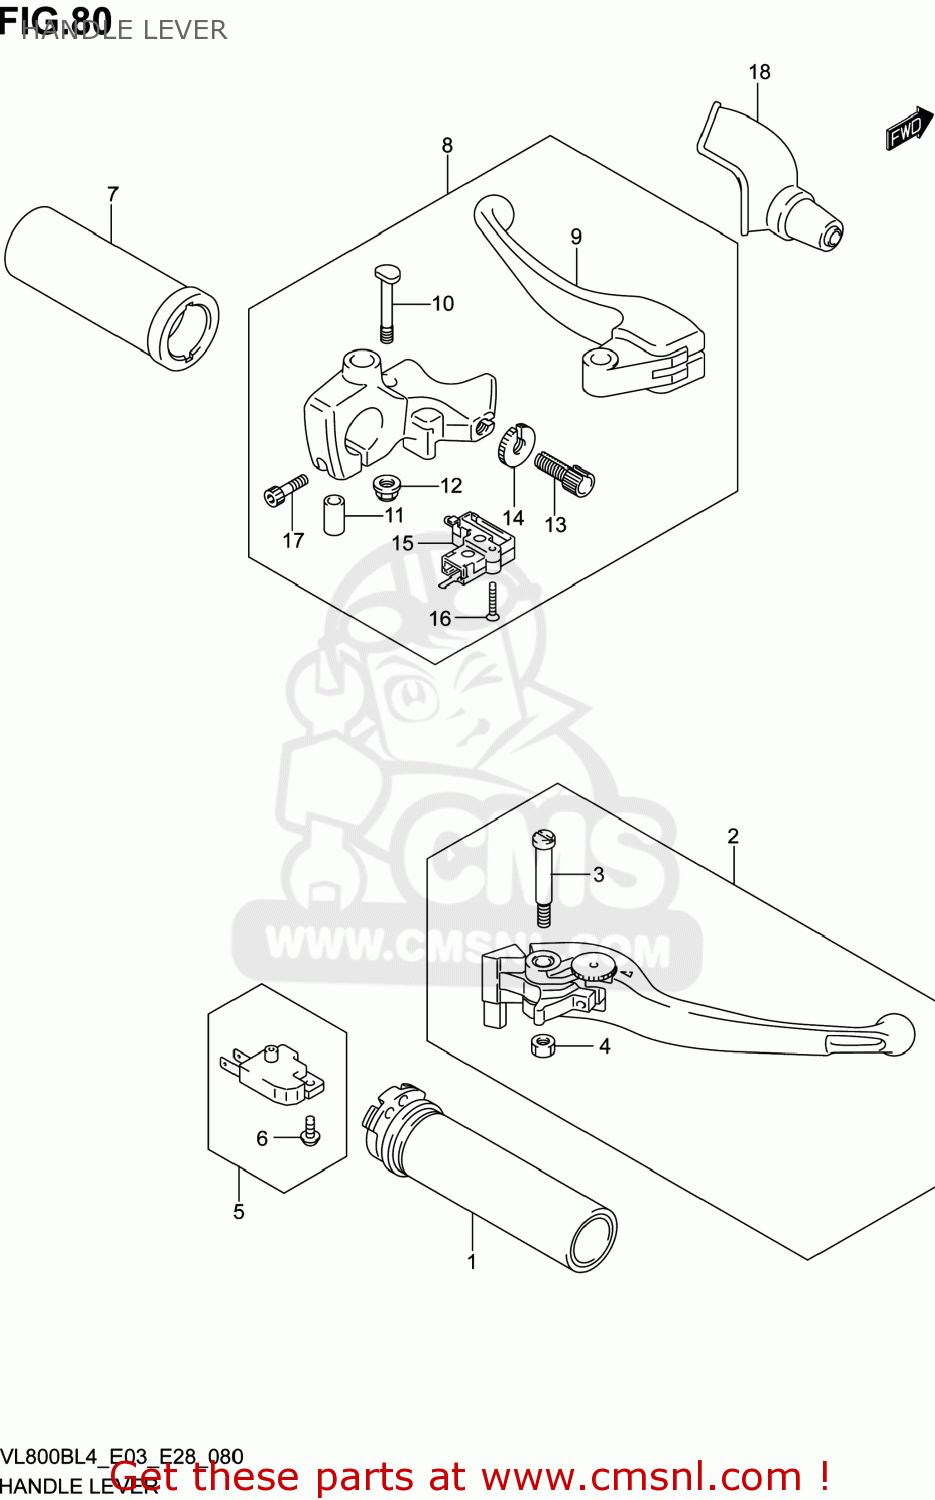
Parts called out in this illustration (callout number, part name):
1	GRIP,THROTTLE
2	LEVER ASSY,BRAKE
3	BOLT,PIVOT
4	NUT
5	SWITCH ASSY,FR BRAKE
6	SCREW
7	GRIP,L
8	LEVER ASSY,CLUTCH
9	LEVER,CLUTCH
10	BOLT,LEVER PIVOT
11	COLLAR
12	NUT
13	ADJUSTER,WIRE
14	NUT,LOCK
15	SWITCH ASSY,CLUTCH
16	SCREW
17	BOLT
18	COVER,CLUTCH LEVER
